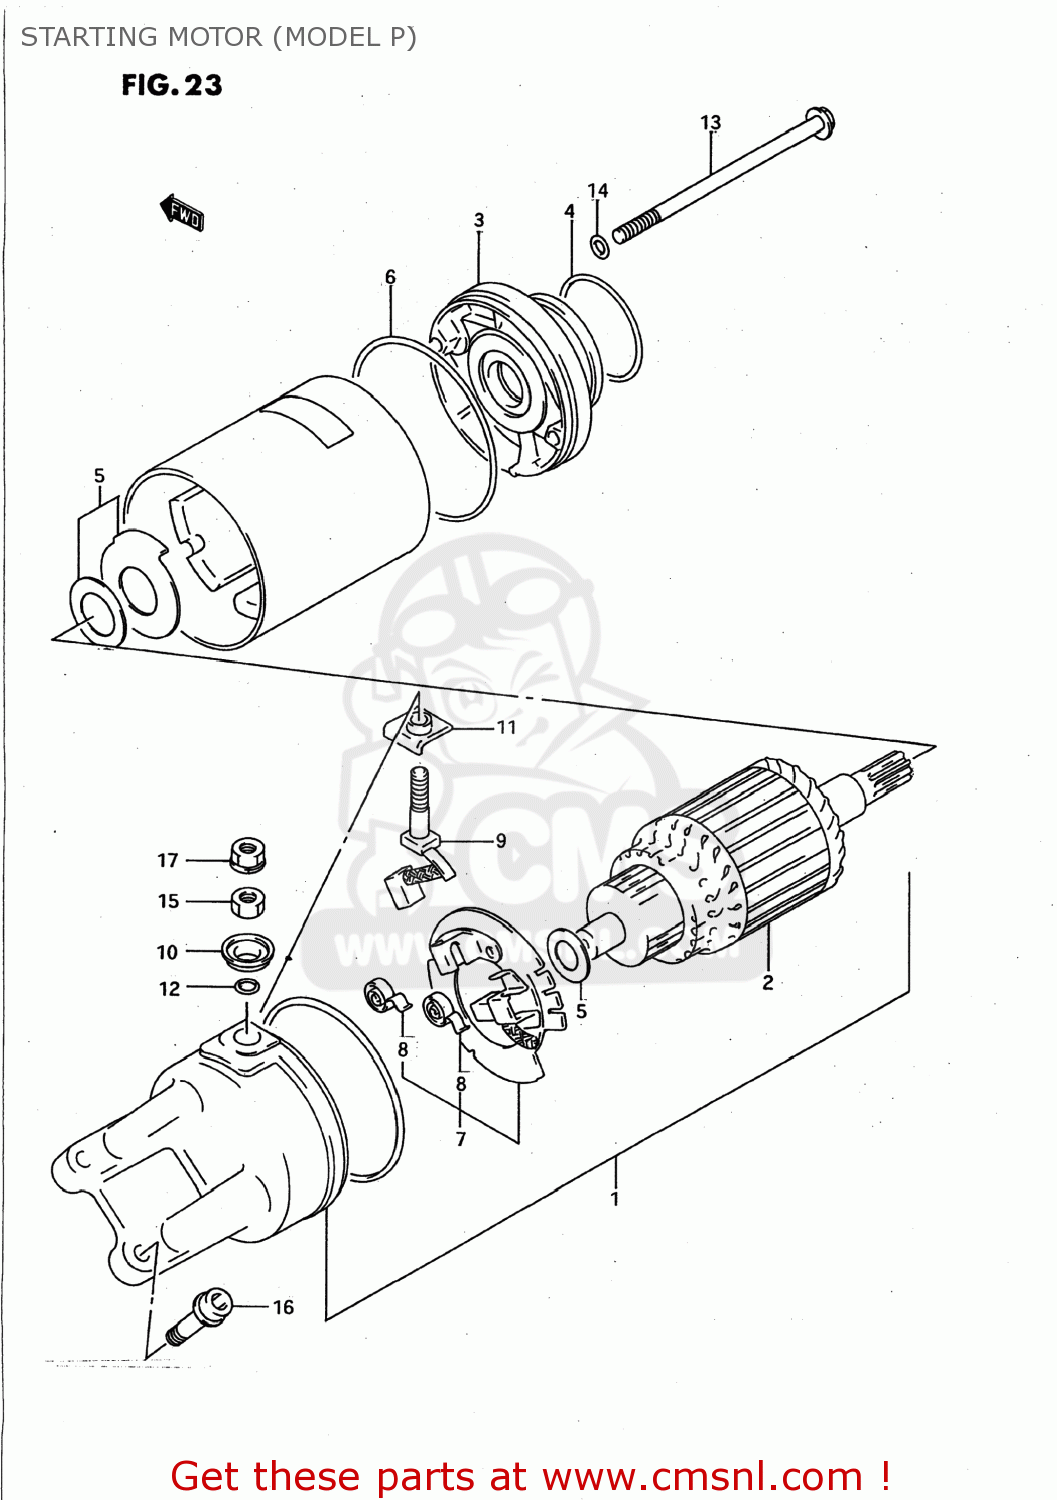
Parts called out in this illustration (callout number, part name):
1	MOTOR ASSEMBLY,STARTING
2	ARMATURE
3	HOUSING
4	O RING
5	SHIM SET,STARTING MOTOR
6	O RING
7	HOLDER,BRUSH
8	SPRING
9	BRUSH SUB ASSY,STARTING MOTOR
10	BUSHING
11	BUSH,B
12	O RING
13	BOLT
14	O RING
15	NUT 6MM
16	BOLT,BRACKET
17	NUT
